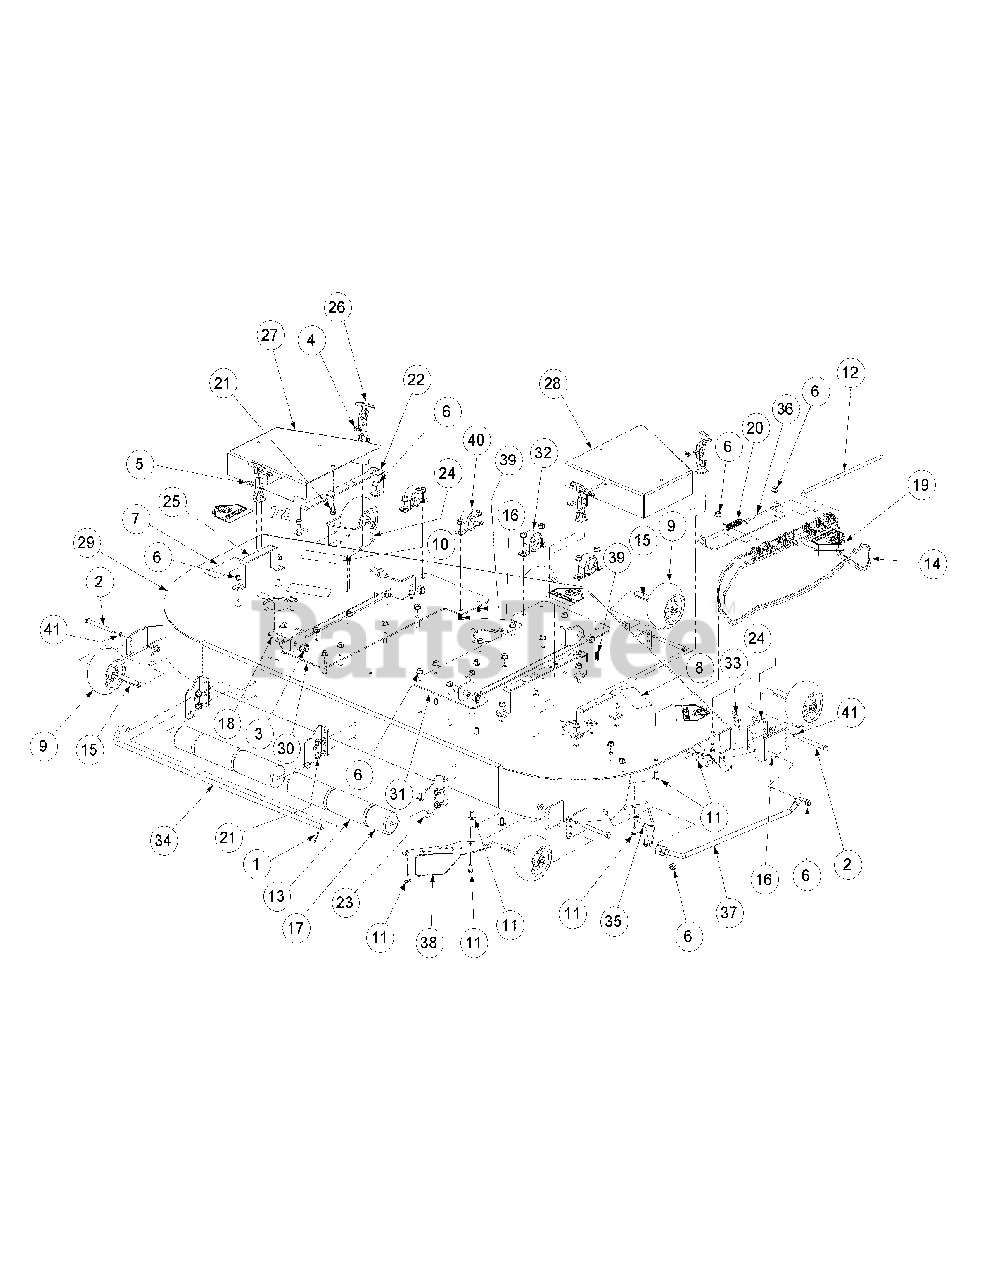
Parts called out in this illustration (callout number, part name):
1	Cotter Pin, .125 Dia. x 1.0
2	Hex Cap Screw, 3/8-16, 3.75
3	Lock Nut, Nylon Insert, 1/2-13
4	Lock Nut, Nylon Insert, #10-32
5	Phillips Head Screw, #10-32 x 1/2
6	Flange Lock Hex Nut, 3/8-16
7	Decal, Rotating Blade
8	Decal, Warning Shield Missing
9	Complete Wheel, 5.00 Dia.
10	Command Cut Large
11	Carriage Bolt, 3/8-16 x .75 Lg.
12	Pin, .375 x 14.06
13	Front Roller
14	Chute Deflector
15	Wheel Spacer
16	Carriage Bolt, 3/8-16 x 1
17	Grass Catcher Roller
18	Pin, 5/8 Dia. x 1.2 Lg.
19	Decal, Danger Hand and Feet
20	Torsion Spring, 0.4ID x 2.16Lg
21	Hex Index Washer Screw, 3/8-16, .5
22	Belt Cover Support
23	Deck Roller Mount Bracket
24	Anti-Scalp Wheel Front Mount Bracket
25	Outer Belt Cover Support Assembly
26	T-Handle Latch Draw
27	Left Hand Deck Belt Cover
28	Right Hand Deck Belt Cover
29	72 Deck Assembly
30	Left Hand Deck Weldment Bracket
31	Right Hand Deck Weldment Bracket
32	Pillow Block, Steel
33	Decal, 72"
34	Roller Pin
35	Chute Bracket
36	Chute Bracket
37	Finger Guard
38	Discharge Baffle Weldment
39	Carriage Screw, 3/8-16 x 1.25
40	Pillow Block, Bronze
41	Flat Washer, 3/8
